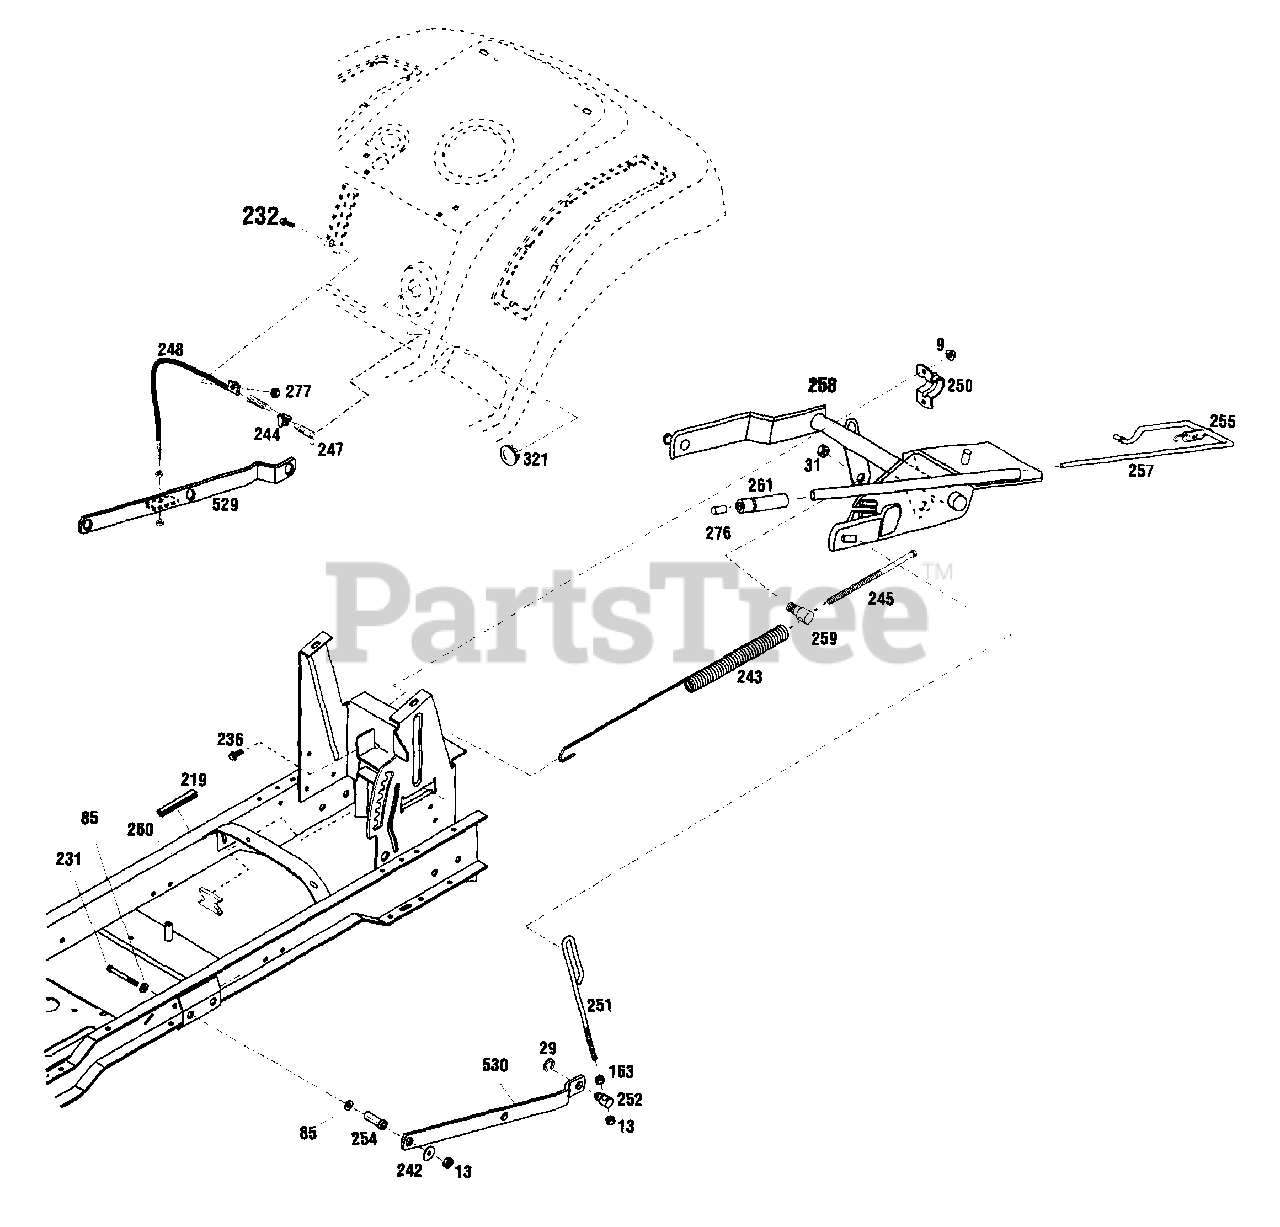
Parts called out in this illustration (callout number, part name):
9	Flange Nut, 5/16-18
13	Hex Top Locknut, 3/8-16
29	Retaining Ring, 5/8
31	Hex Top Locknut, 5/8-11
85	Flat Washer, 3/8
163	Hex Nut, 3/8-16
231	Hex Head Screw, 3/8-16 x 3
232	Screw, 10-24 x 5/16
236	Flange Screw, 5/16-18 x 3/4
242	Flat Washer, 3/8 x 1-1/2
243	Lift Assist Spring
244	Height Indicator
245	Lift Assist Screw
247	Extension Spring
248	Cable Assembly
250	Lift Clamp
252	Rear Lift Swivel
255	Extension Spring
258	Lift Assembly
259	Pivot Block
260	Spring Anchor
261	Lift Grip
276	Lift Button
277	Keps Nut, 10-24
529	Right Lift Link Assembly
530	Left Lift Link Assembly
